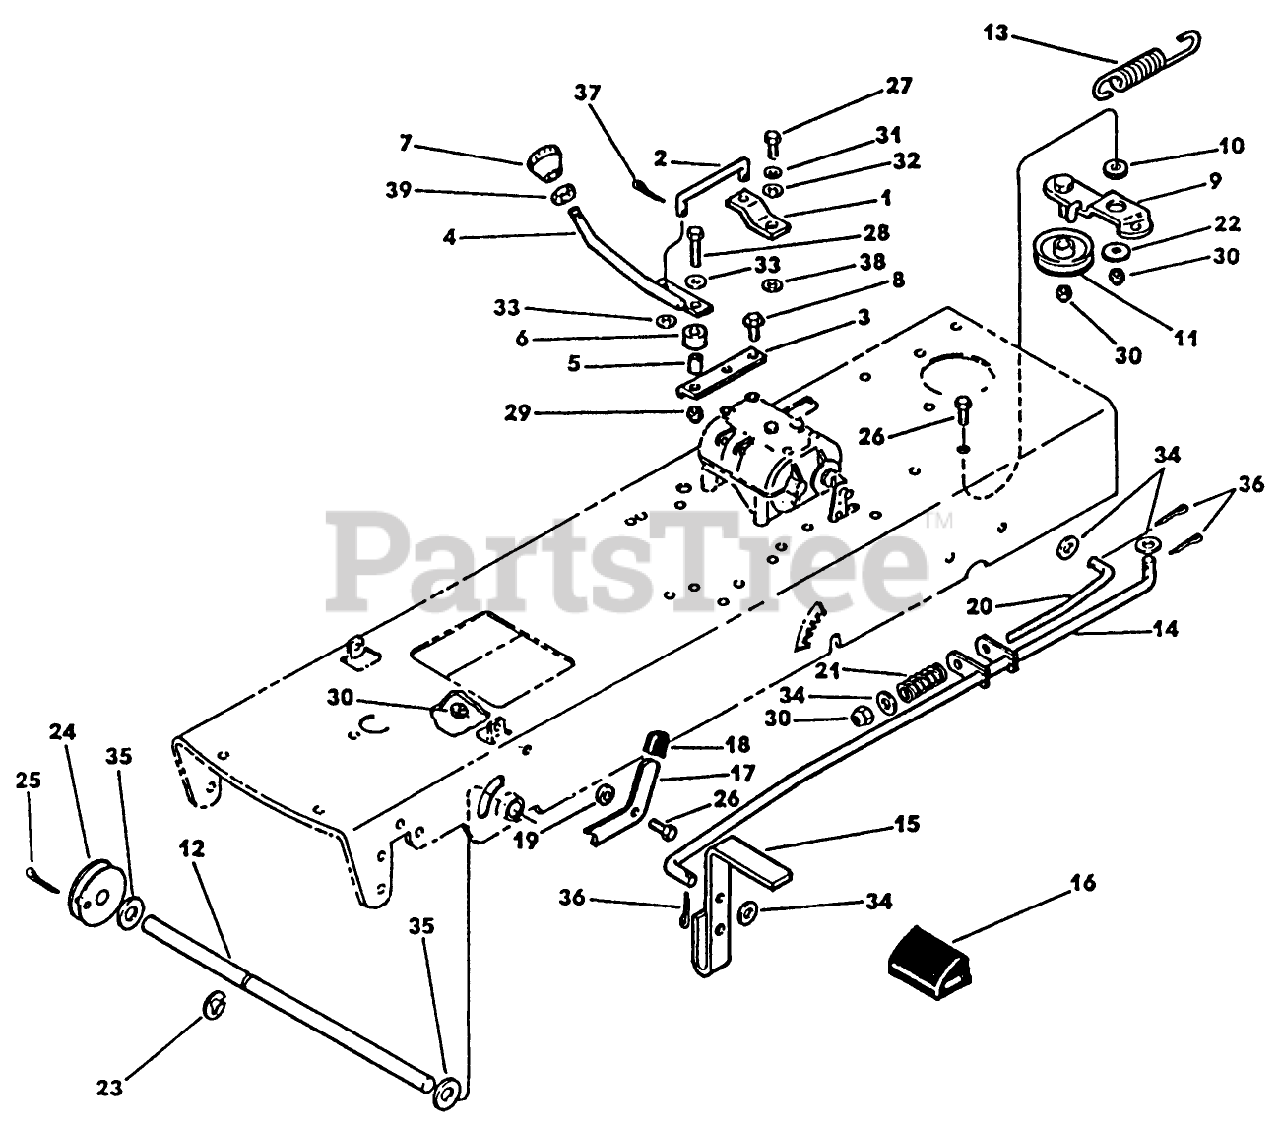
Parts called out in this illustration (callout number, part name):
1	PLATE-SHIFTER
3	BRKT - SHIFT MOUNT *B
5	SPACER
6	SPACER - RUBBER
8	SCREW
12	SHAFT - CROSS
13	SPRING
16	PAD - FOOT
20	701617BRAKE (PLATED)
27	SCREW-HEXHEAD
29	NUT
30	NUT-LOCKING
32	WASHER
34	WASHER
39	NUT-HEX
